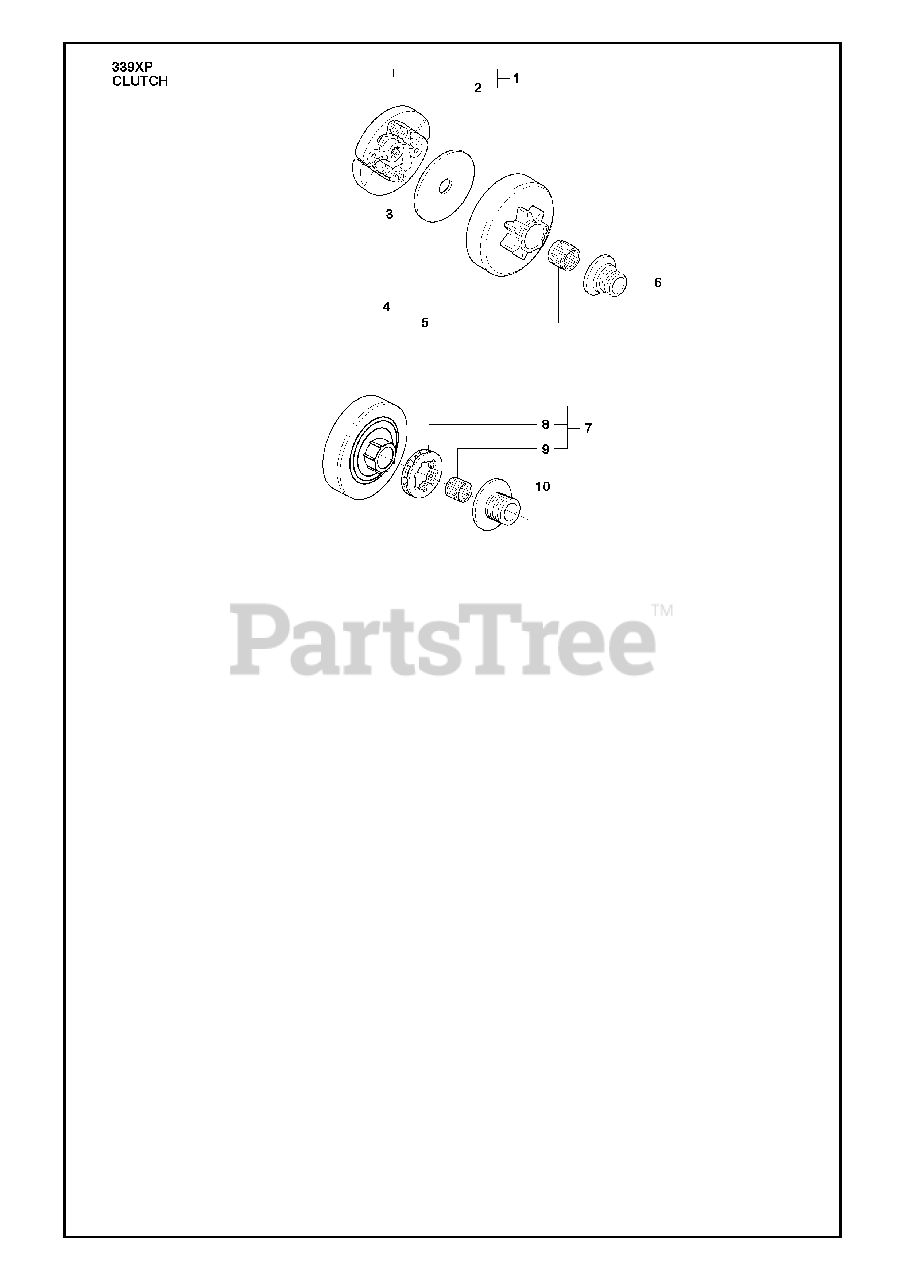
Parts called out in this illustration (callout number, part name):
4	CLUTCH DRUM
4	CLUTCH DRUM 3/8
4	CLUTCH DRUM .325
5	NEEDLE BEARING
6	OIL PUMP PINION
6	PINION
7	CLUTCH DRUM CPL
8	RIM SPROCKET 7T .325
9	NEEDLE BEARING
10	WORM GEAR
